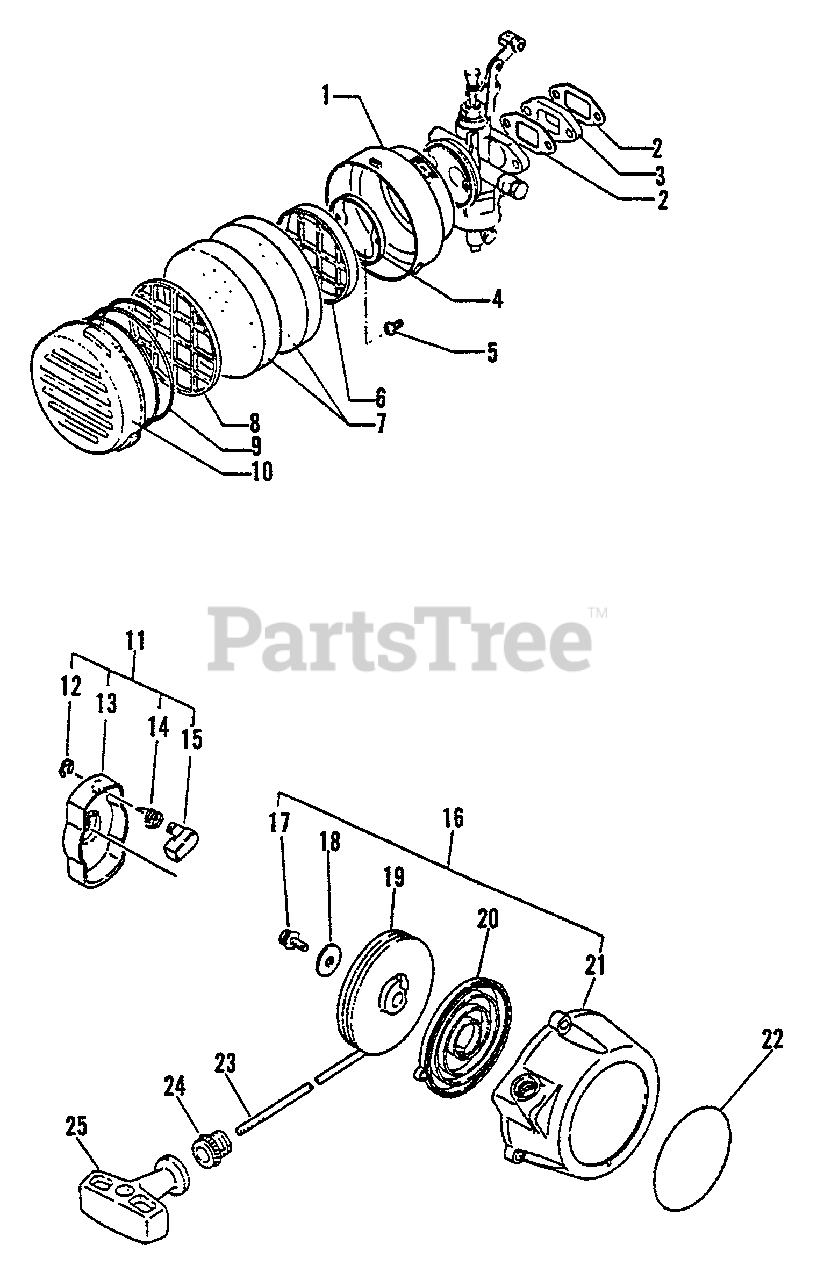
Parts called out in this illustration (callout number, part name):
1	CASE, AIR FILTER
2	GASKET, INTAKE
3	INSULATOR, INTAKE
4	BRACKET, AIR CLEANER
5	SCREW - 4X14
6	RETAINER, AIR FILTER
7	FILTER, AIR
8	RETAINER, AIR FILTER
10	COVER, AIR FILTER
11	STARTER PAWL ASSY
12	RING, RETAINING - 6
13	CATCHER, PAWL
14	SPRING, RETURN
15	PAWL, STARTER
16	STARTER ASSY
19	REEL, ROPE
20	SPRING, REWIND
21	CASE, STARTER
22	LABEL - ECHO
22	LABEL - MODEL
23	ROPE, STARTER - 4X880
24	GUIDE, ROPE
25	GRIP, STARTER
